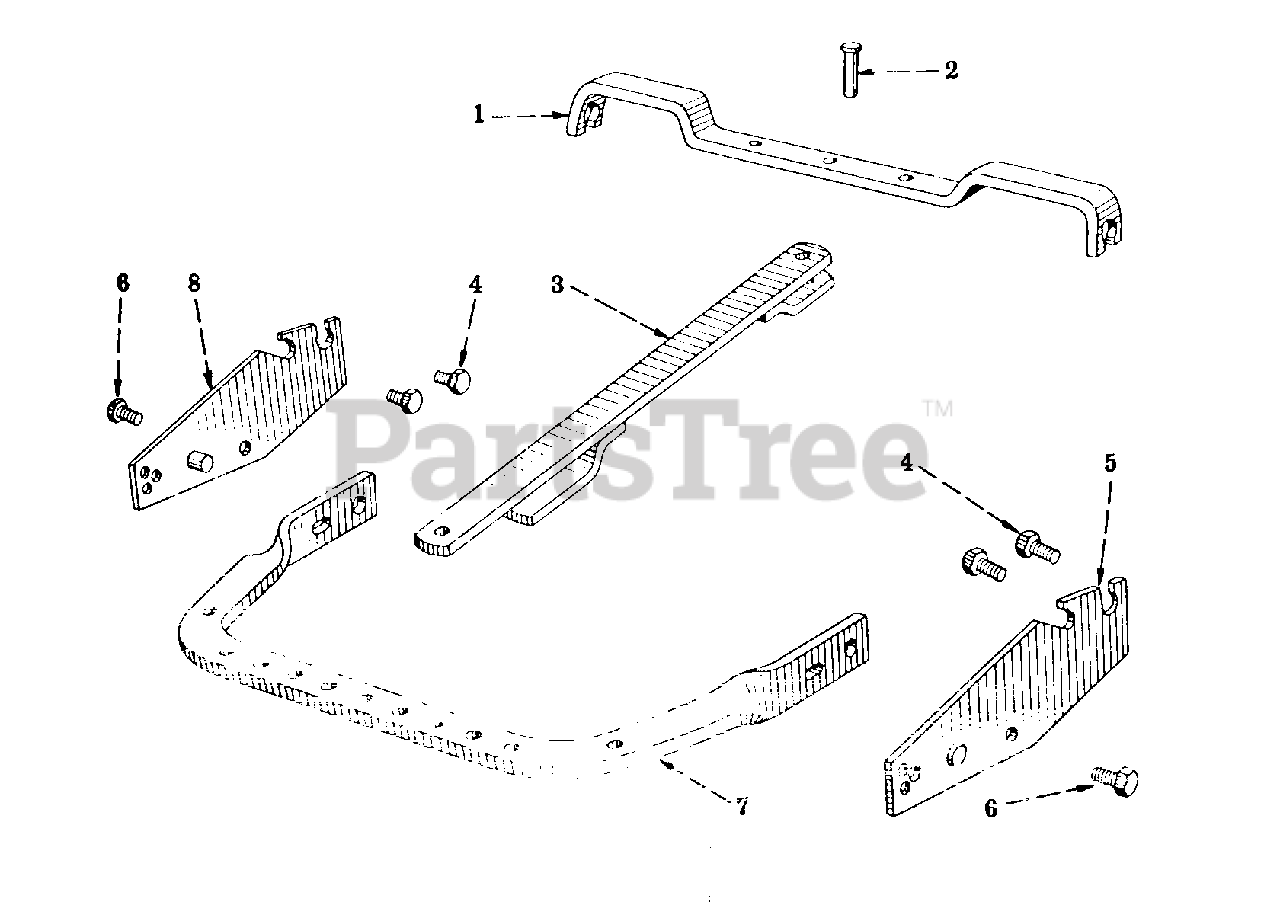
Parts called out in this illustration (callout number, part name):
1	BAR, SWINGING DRAWBAR ANCHOR
2	PIN, SWINGING DRAWBAR PIVOT
3	DRAWBAR ASSY, SWINGING
4	BOLT, DRAWBAR BRACKET
5	BRACKET ASSY, QUICK ATTACHABLE DRAWBAR RH
6	BOLT, SWINGING DRAWBAR ANCHOR BAR
7	DRAWBAR, QUICK ATTACHABLE
8	BRACKET ASSY, QUICK ATTACHABLE DRAWBAR LH
